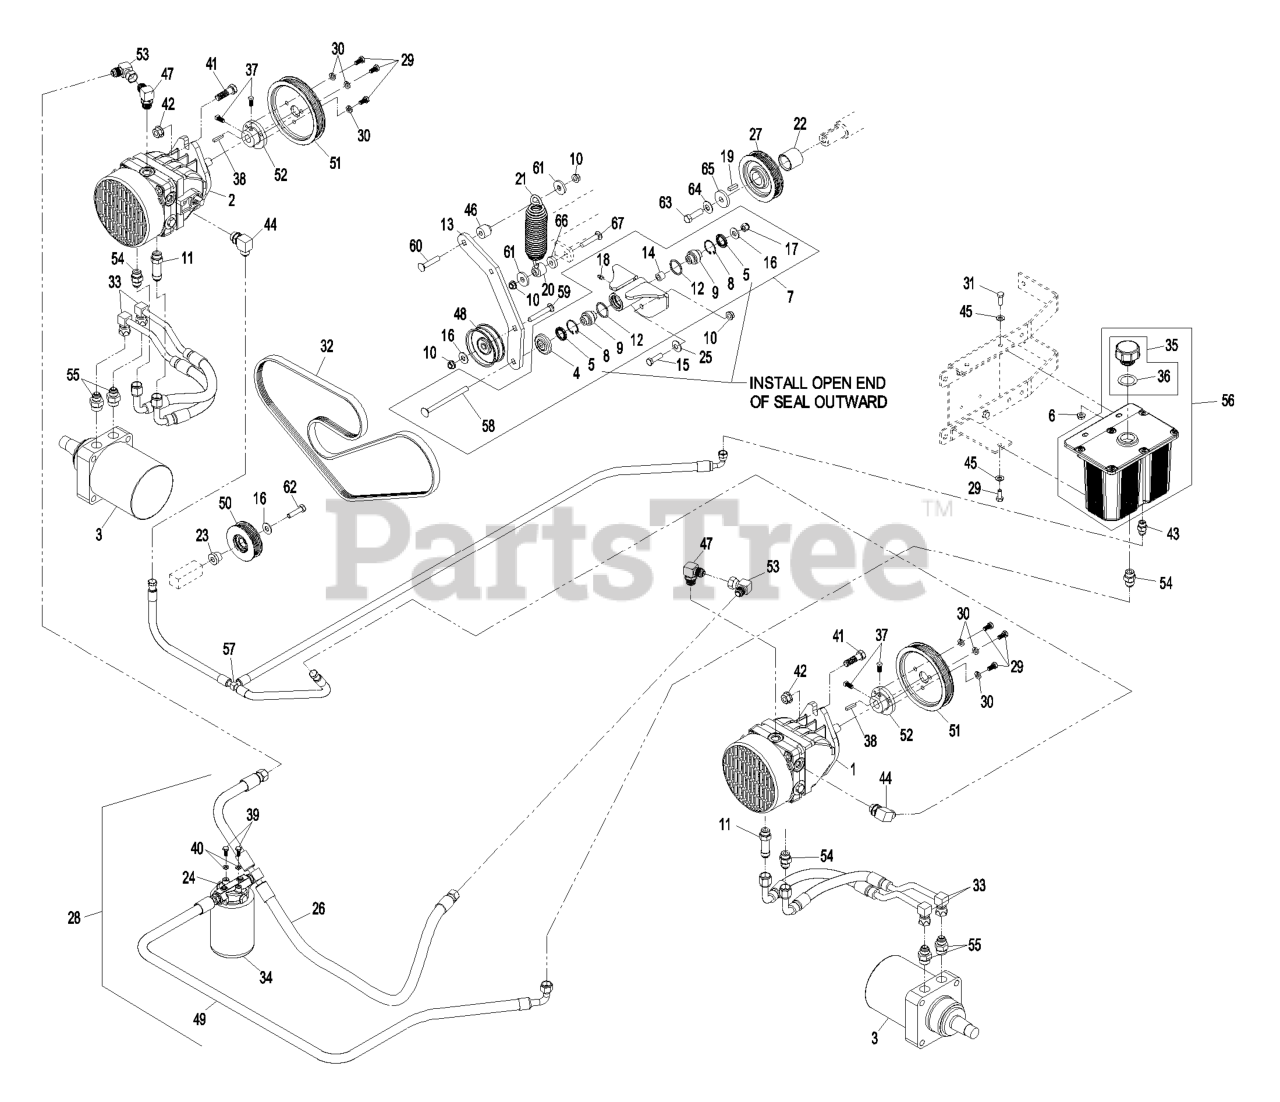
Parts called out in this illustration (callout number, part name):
4	GUARD-TOP
5	SEAL-LIP, SINGLE
7	KIT,XS PUMP IDLER
8	RING-SNAP
9	BEARING-SPHERICAL
10	NUT-HHF, WHIZ
11	ADAPTER-STR, LONG
13	ARM, XS HYDRO TIGHTENER
15	SCREW-HH
16	WASHER-FLAT
17	NUT-LOCK, NI
18	FITTING-GREASE
19	KEY-SQUARE
20	SPACER-SPRING, FAN PUMP
22	SPACER,ENGINE SHEAVE
23	SPACER,LOWER FRAME IDLER
24	HEAD-FILTER
25	WASHER-BELLEVILLE
26	HOSE,31 EPS PUMP INLET
27	SHEAVE,5K 4"PD POLY-V
29	SCREW-HH
30	WASHER-LOCK
31	SCREW-HH
32	BELT,PVK 5 X 70.5
33	HYD HOSE ASM
34	FILTER,XP HYD 25 MICRON
35	KIT,HYD RES CAP W/GASKET
36	GASKET-CAP
37	SCREW-SET
39	SCREW-HH
40	WASHER-LOCK
41	SCREW-HH
42	NUT-HHF
43	FITTING-STRAIGHT
44	FITTING-ELBOW, 90 DEG
45	WASHER-PLAIN
47	FITTING-90 DEG
48	IDLER,PUMP
50	ASM,LOWER FRAME IDLER
51	SHEAVE,5K 5.6" PD POLY-V
52	HUB-PUMP
53	FITTING-90 DEG
54	FITTING-STRAIGHT
55	FITTING-STRAIGHT
56	HYDRAULIC TANK ASM
57	ASM,CASE DRAIN HOSE
58	BOLT CARR 3/8-16X5
59	SCREW-CARR
60	SCREW-CARR
62	SCREW-HH
63	SCREW-HH
64	WASHER-SPRING
65	WASHER-CLUTCH
66	SPACER-BRACKET, GUIDE
67	BOLT-CARR, SHORT NECK
68	KIT,HYD RES CAP W/GASKET
